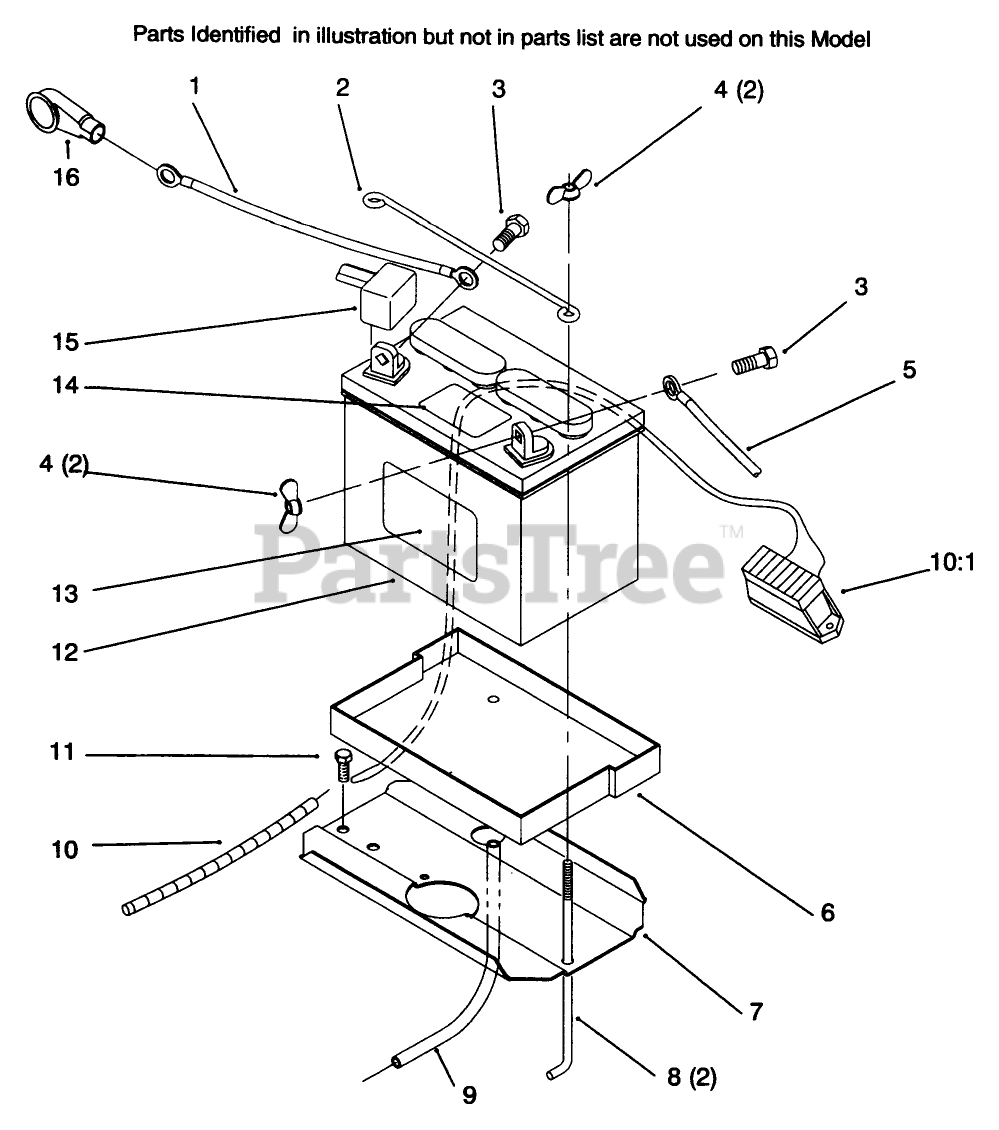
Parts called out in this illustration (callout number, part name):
1	WIRE -10" RED
2	ROD-BATTERY HOLD DWN
3	SCREW-HH
4	NUT-WING
5	WIRE -BLACK
6	TRAY-BATTERY
7	PLATE-BATTERY
9	TUBE-21" BATTERY DRAIN
11	SCREW-HWHTF
